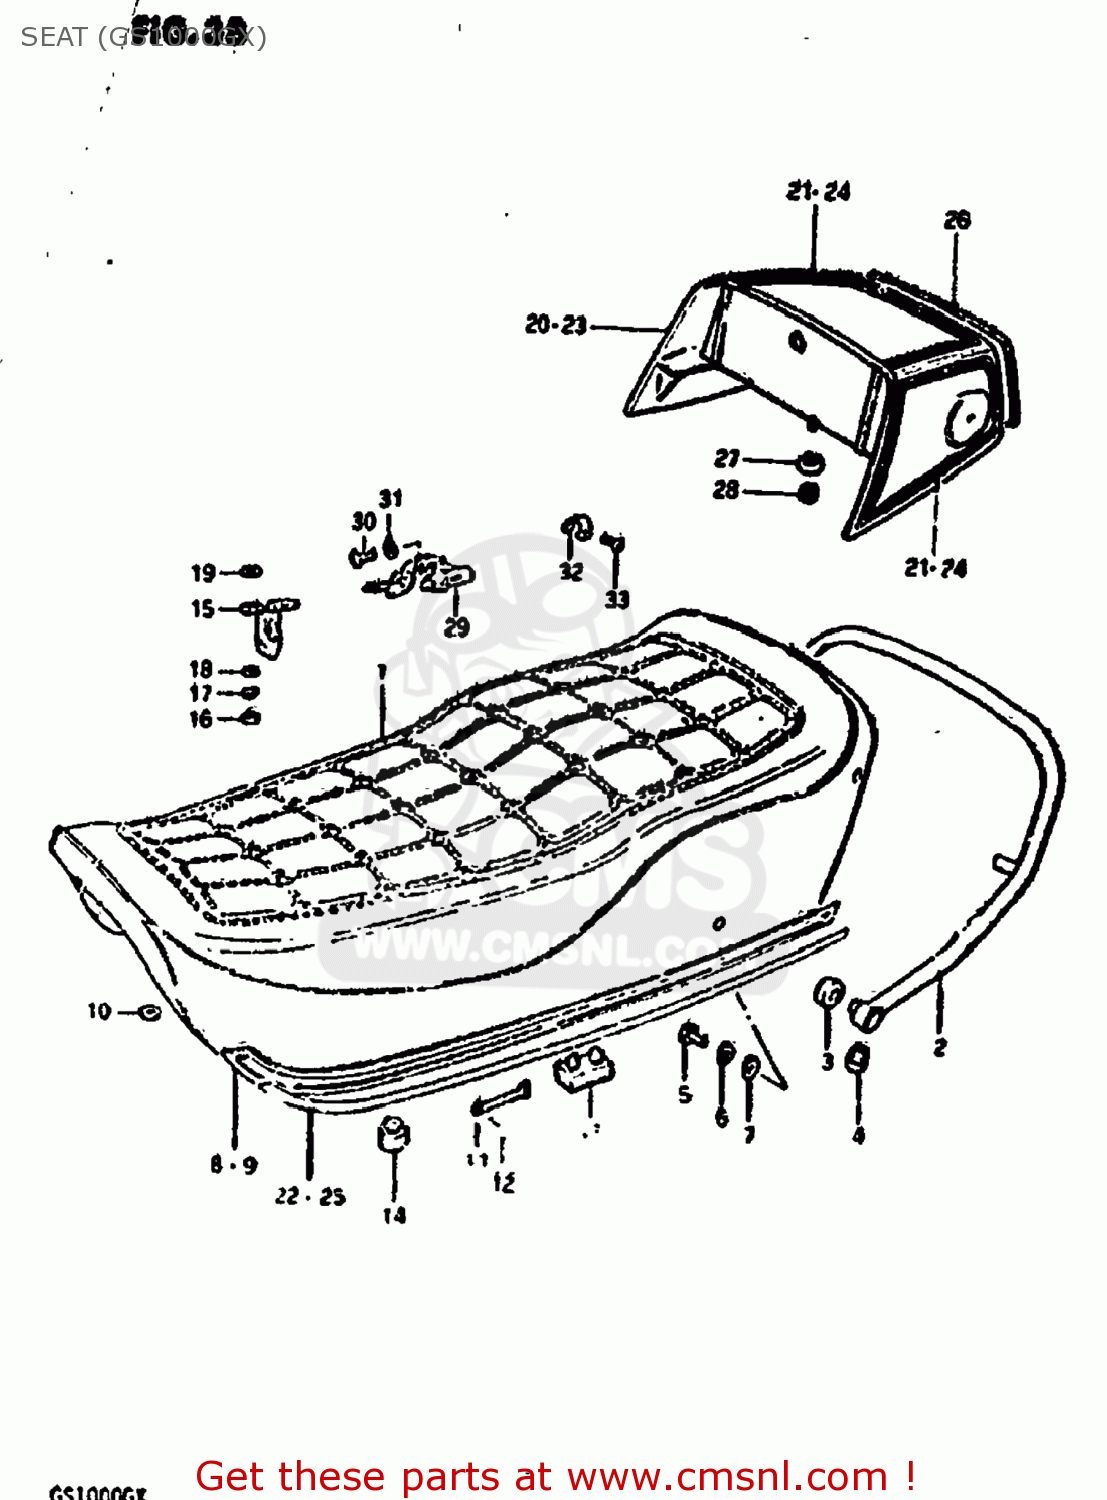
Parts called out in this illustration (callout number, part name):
1	SEAT ASSEMBLY
2	HANDLE,PILLION RIDER
3	CUSHION
4	END,SHEET HANDLE
5	BOLT
6	LOCK WASHER
7	WASHER
8	MOLE,R
9	MOLE,L
10	NUT
11	PIN
12	PIN
13	CUSHION
14	CUSHION
15	STRIKER,SEAT LOCK
16	NUT
17	LOCK WASHER
18	WASHER 6MM
19	WASHER (6.5X20X1.2)
20	BOX SET,SEAT TAIL
21	TAPE SET,SEAT TAIL COVER
22	TAPE SET
23	BOX SET,SEAT TAIL
24	TAPE SET,FUEL TANK
25	TAPE SET
26	MOLDING,SEAT TAIL COVER
27	WASHER
28	NUT 6MM
29	LOCK ASSY,SEAT
30	SCREW
31	LOCK WASHER
32	SPRING,HELMET HOLDER
33	SCREW
